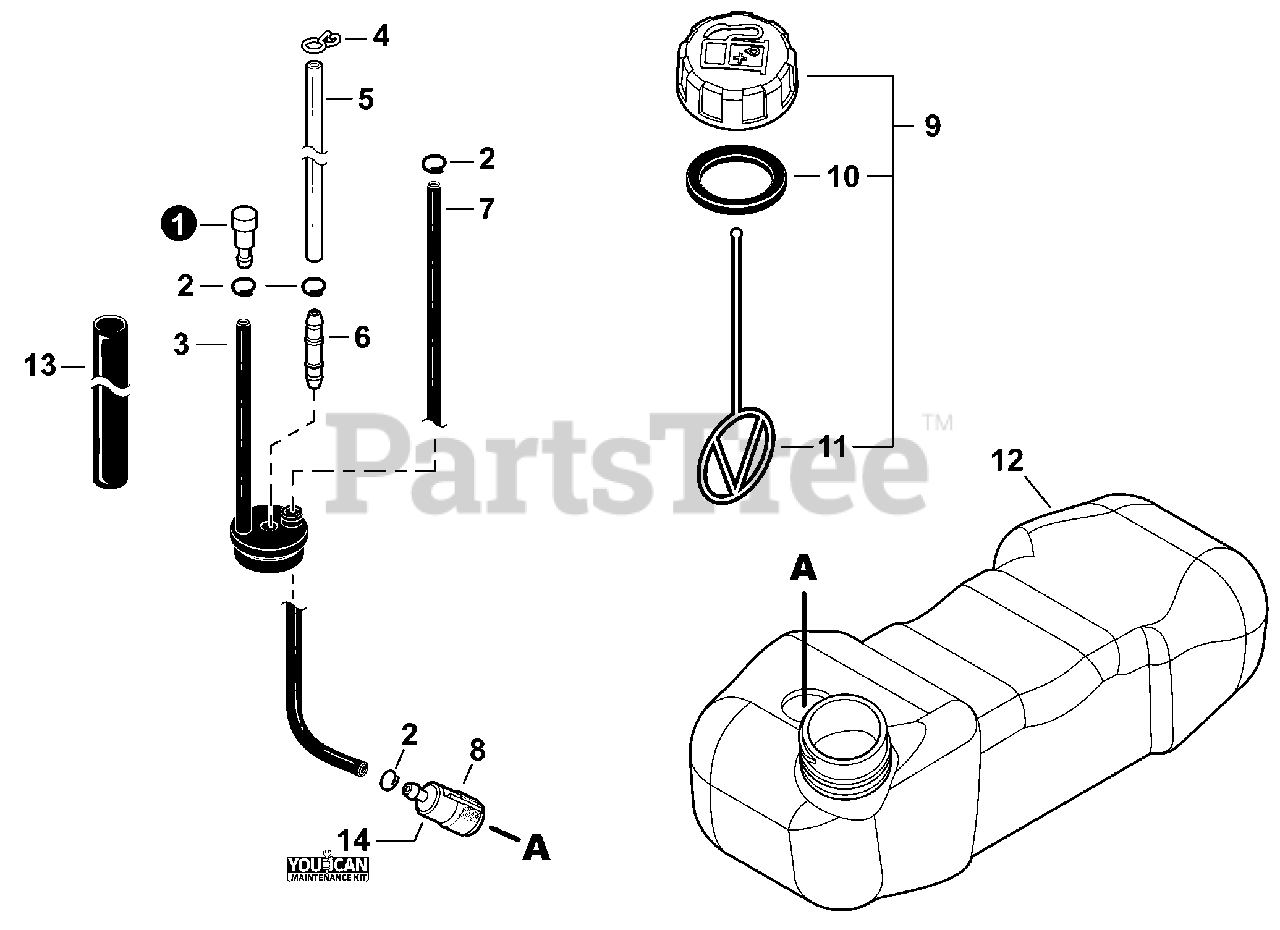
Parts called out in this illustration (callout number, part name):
1	VENT ASSY
2	CLIP Ø6
3	GROMMET, FUEL W/VENT PIPE
4	CLIP, SPRING Ø5.2
5	PIPE, FUEL 3×6×133 CLEAR
6	CONNECTOR, PIPE
7	PIPE, FUEL
8	FILTER, FUEL 125-528
9	CAP ASSY, FUEL
10	GASKET, FUEL CAP
11	CONNECTOR, CAP L= 100mm
12	TANK, FUEL
13	TUBE, PROTECTIVE
14	TUNE-UP KIT - YOUCAN™
